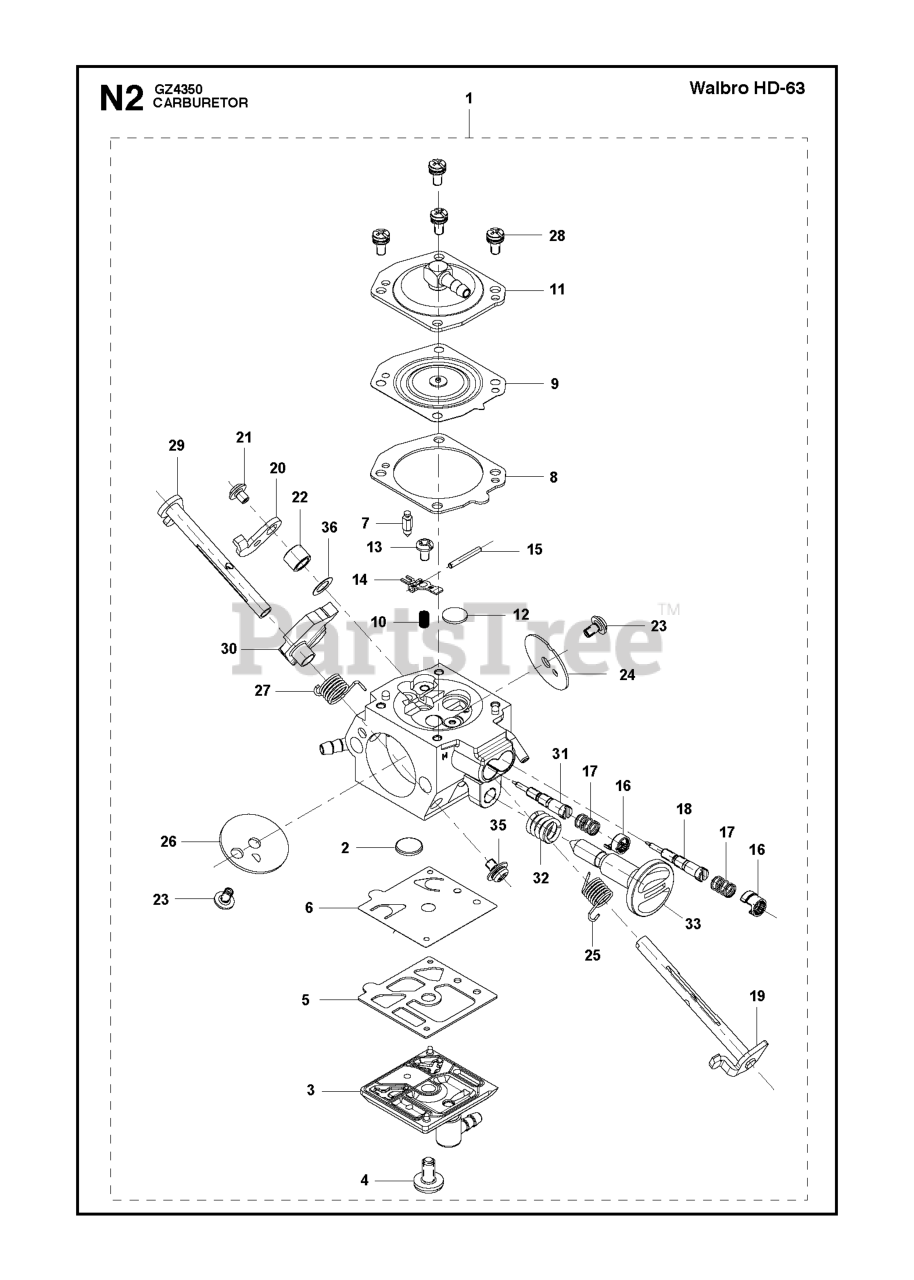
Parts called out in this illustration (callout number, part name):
1	CARBURETTOR ASSY
2	SCREEN
3	COVER ASSEMBLY PUMP 21-3780
4	SCREW Z149181130
6	DIAPHRAGM PUMP
7	VALVE INLET
9	DIAPHRAGM ASSEMBLY METERING 95
10	SPRING
11	COVER PUMP
16	CAP LIMITER
19	SHAFT ASSY THROTTLE 22-4282
20	LEVER THROTTLE 18-3551
21	SCREW
22	SPACER THROTTLE LEVER 148-96
23	SCREW 96-3240
24	VALVE THROTTLE 34-314
25	SPRING 98-3706
26	VALVE CHOKE 34-3504
27	SPRING 98-3718
28	SCREW ASSY
29	SHAFT ASSY CHOKE 22-4356
30	LEVER FAST IDEL 18-3566
31	NEEDLE HIGH SPEED
33	SCREW Z285082310
36	WASHER
